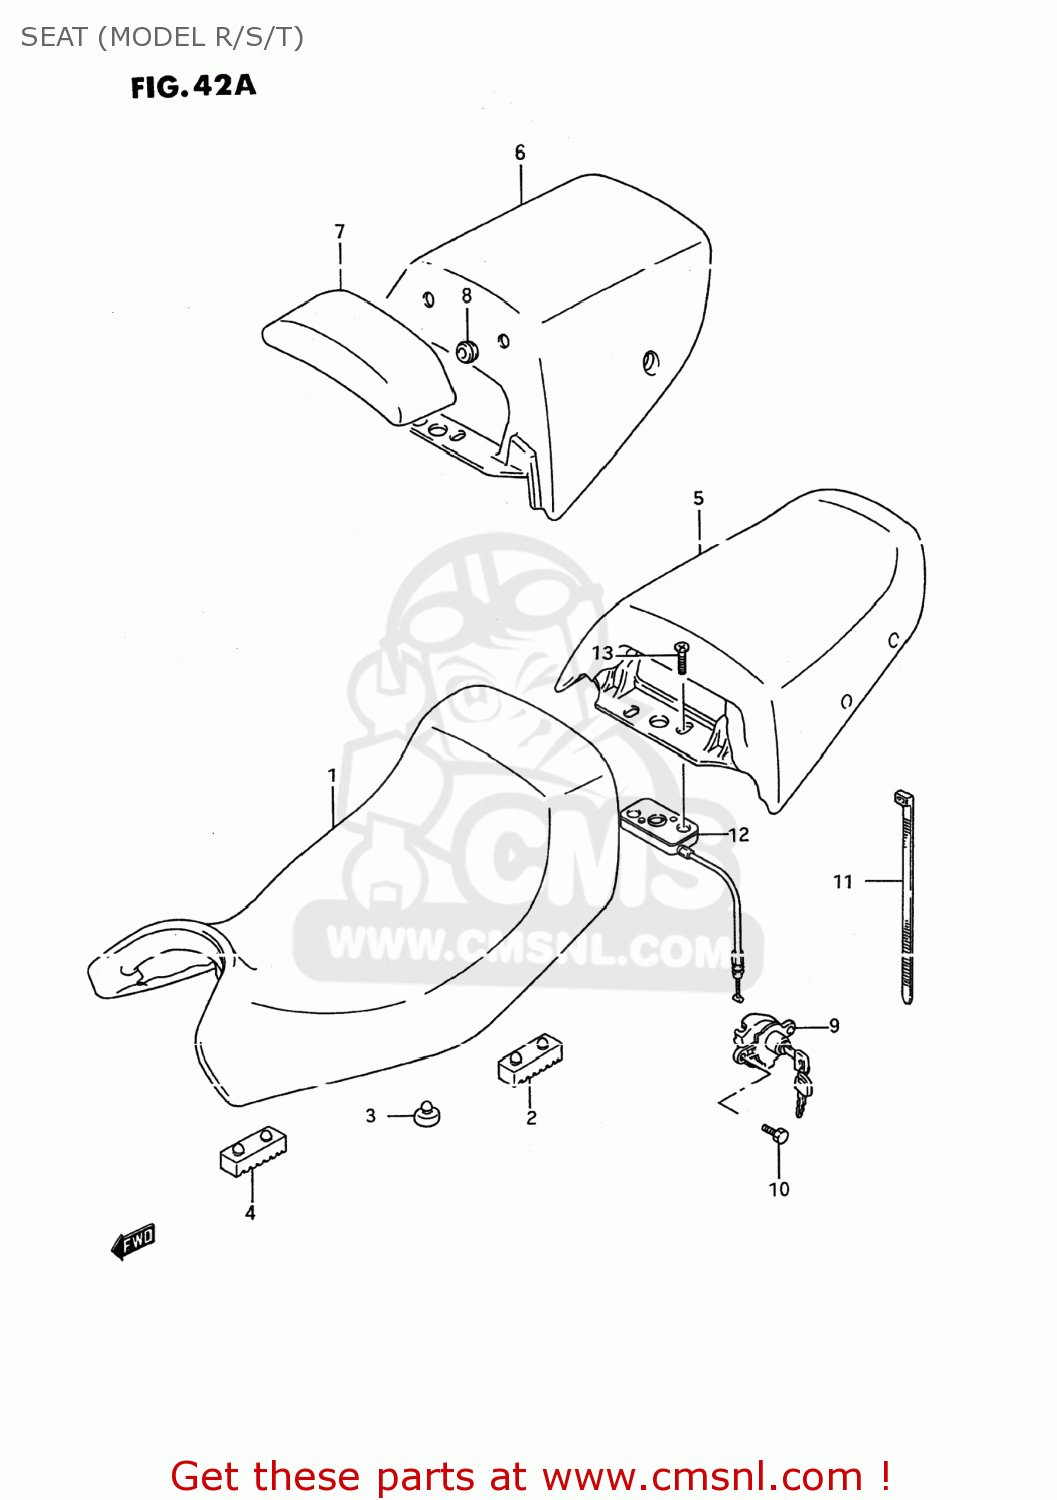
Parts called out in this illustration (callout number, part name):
1	SEAT SET
2	CUSHION,SEAT
3	CUSHION
4	CUSHION,SEAT(40X20X15)
5	SEAT SET,PILLION
6	TAIL COVER SET
7	PAD ASSEMBLY,TAIL COVER
8	CUSHION
9	LOCK SET,SEAT
10	BOLT
11	CLAMP L:165
12	BRACKET,SEAT SUPPORT RR
13	SCREW
